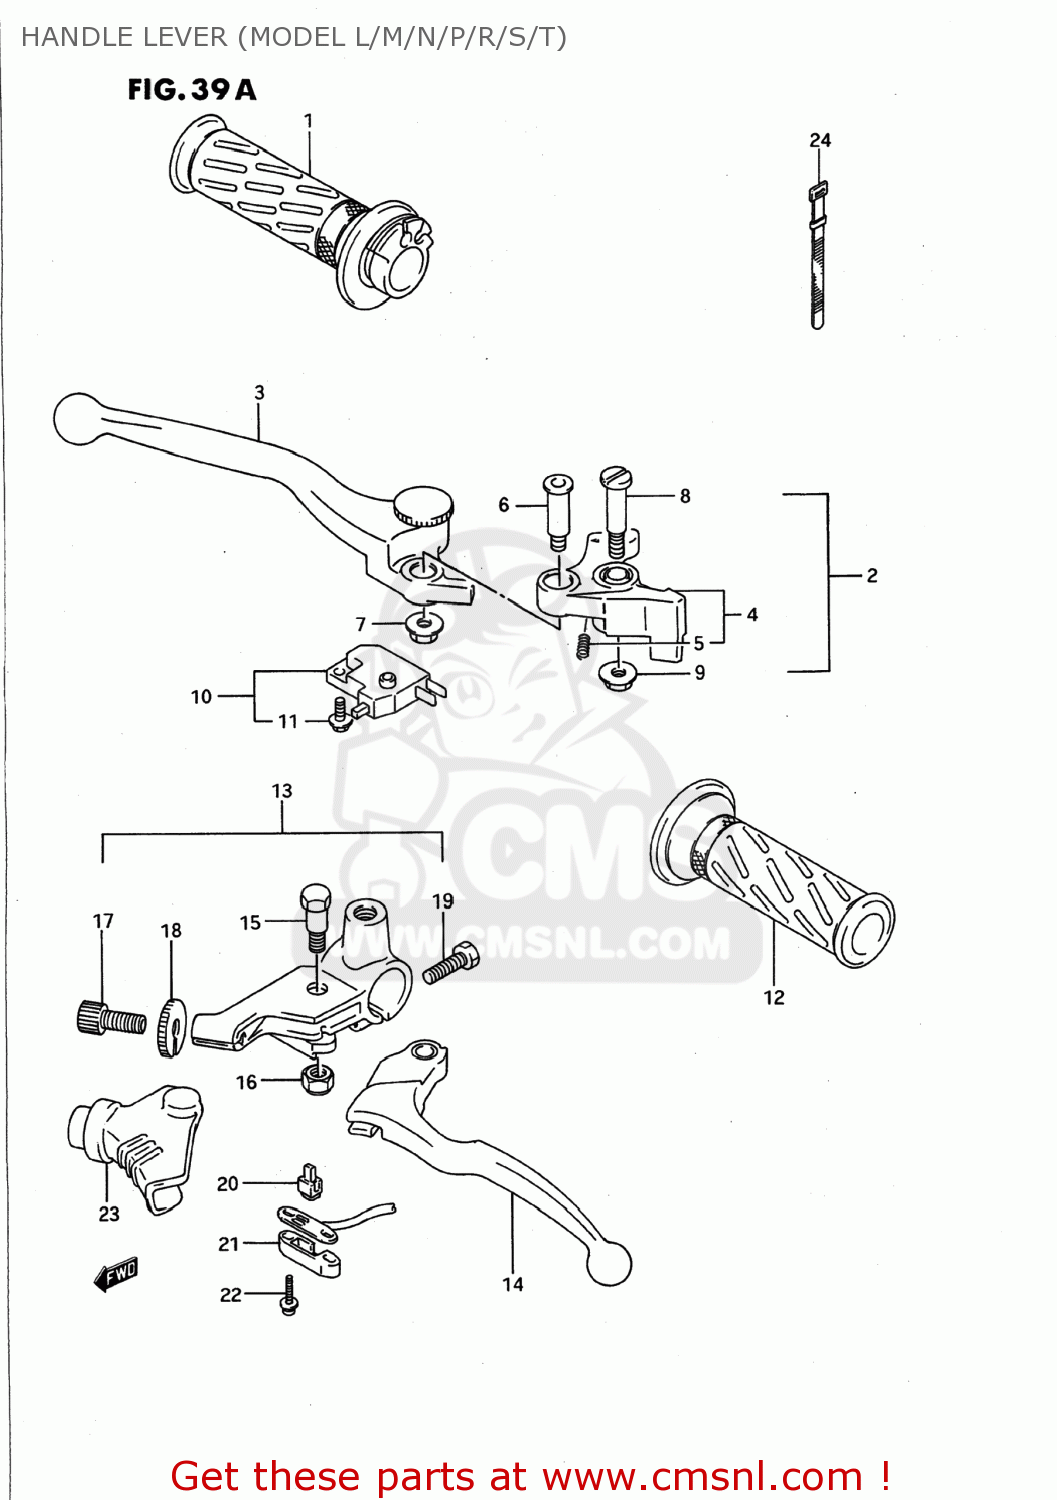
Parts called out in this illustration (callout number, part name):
1	GRIP,THROTTLE
2	LEVER ASSEMBLY,BRAKE
3	LEVER,ADJUST
4	KNOCKER
5	SPRING
6	BOLT,LEVER
7	NUT
8	BOLT,LEVER PIVOT
9	NUT 6MM
10	SWITCH ASSEMBLY,STOP
11	SCREW
12	GRIP,L
13	LEVER ASSY,CLUTCH
14	LEVER,CLUTCH
15	BOLT,LEVER SET
16	NUT
17	ADJUSTER,CABLE
18	NUT,CABLE ADJUSTER
19	BOLT
20	CONTACT,SWITCH
21	COVER,FR BK TERMINAL BASE
22	SCREW
23	COVER,CLUTCH LEVER
24	CLAMP(L:120)
